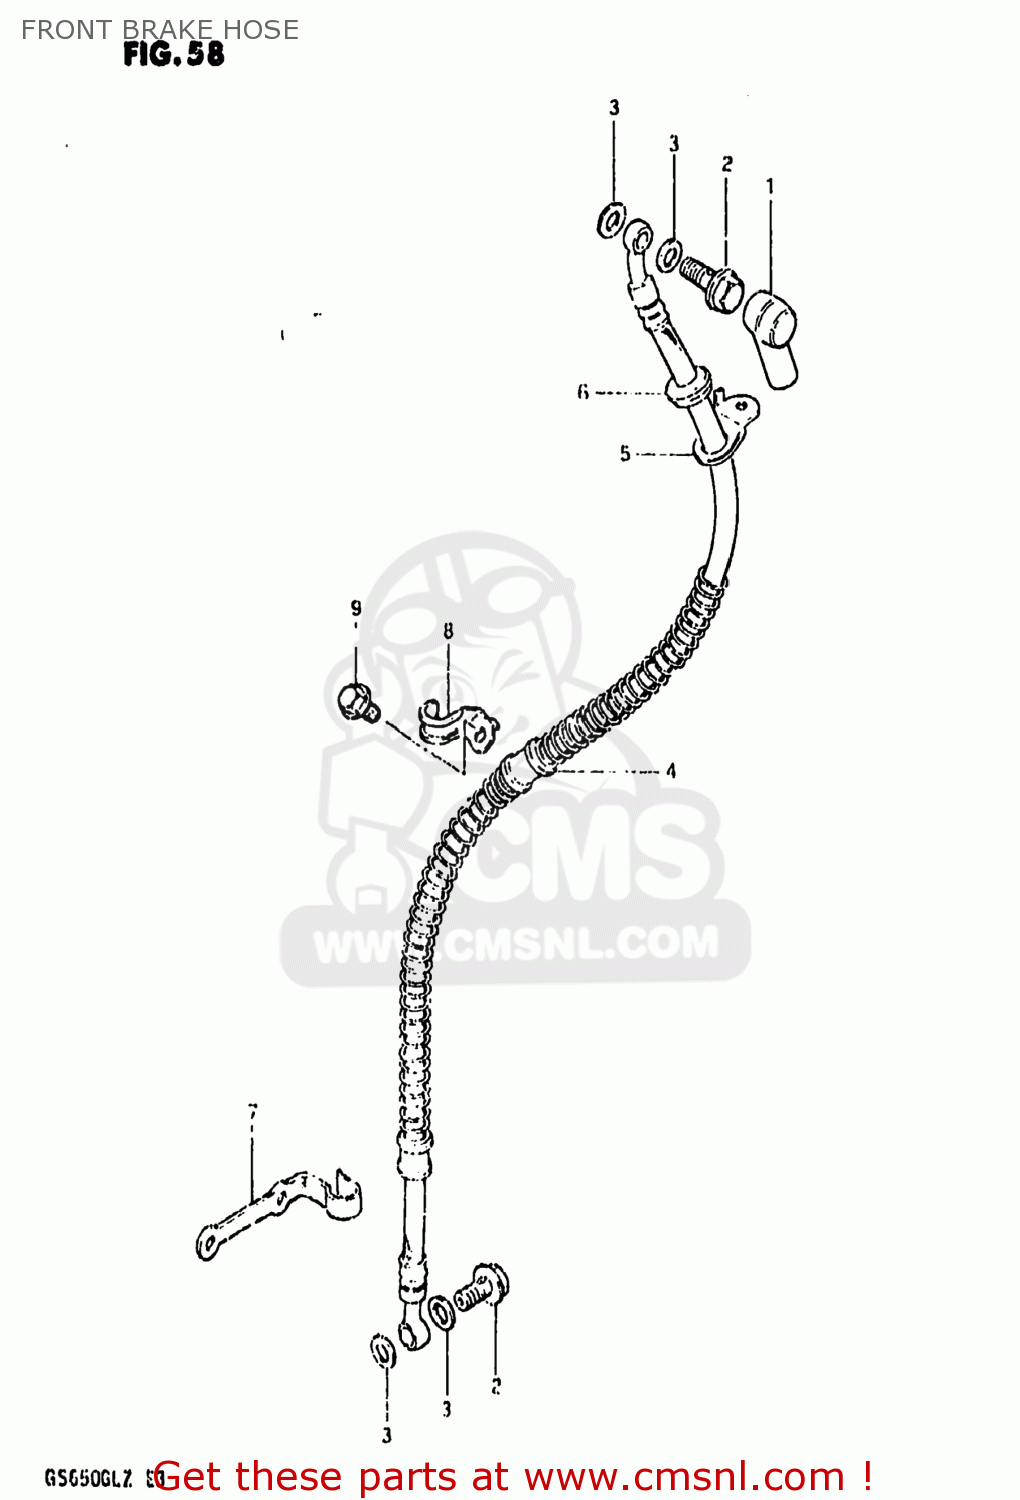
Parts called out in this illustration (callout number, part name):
1	BOOT,MASTER CYLINDER
2	BOLT,UNION
3	WASHER
4	HOSE,FRONT BRAKE
5	GUIDE,BRAKE HOSE
6	GROMMET
7	GUIDE,BRAKE HOSE NO.2
8	GUIDE,BRAKE HOSE NO.3
9	BOLT
